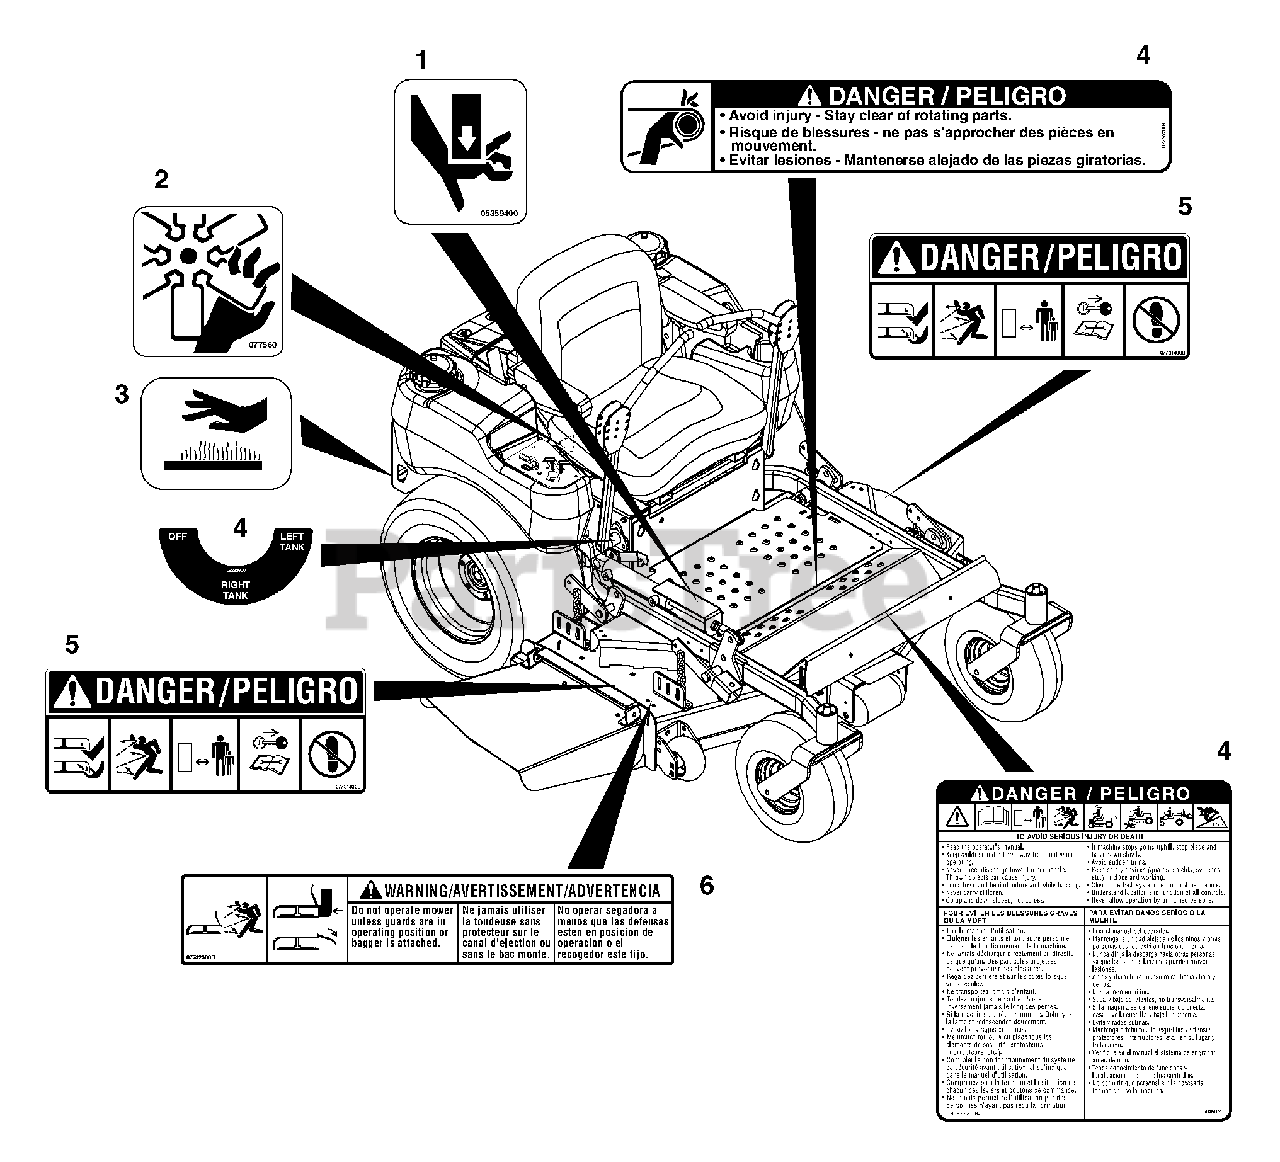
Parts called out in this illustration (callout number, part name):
1	DECAL, PINCH POINT
2	DECAL, DANGER FAN
3	DECAL, HOT SURFACE
4	SET-DECAL, COMMON DANGER/FUEL
5	DECAL, MOWER PAN DANGER
6	DECAL, WARNING
